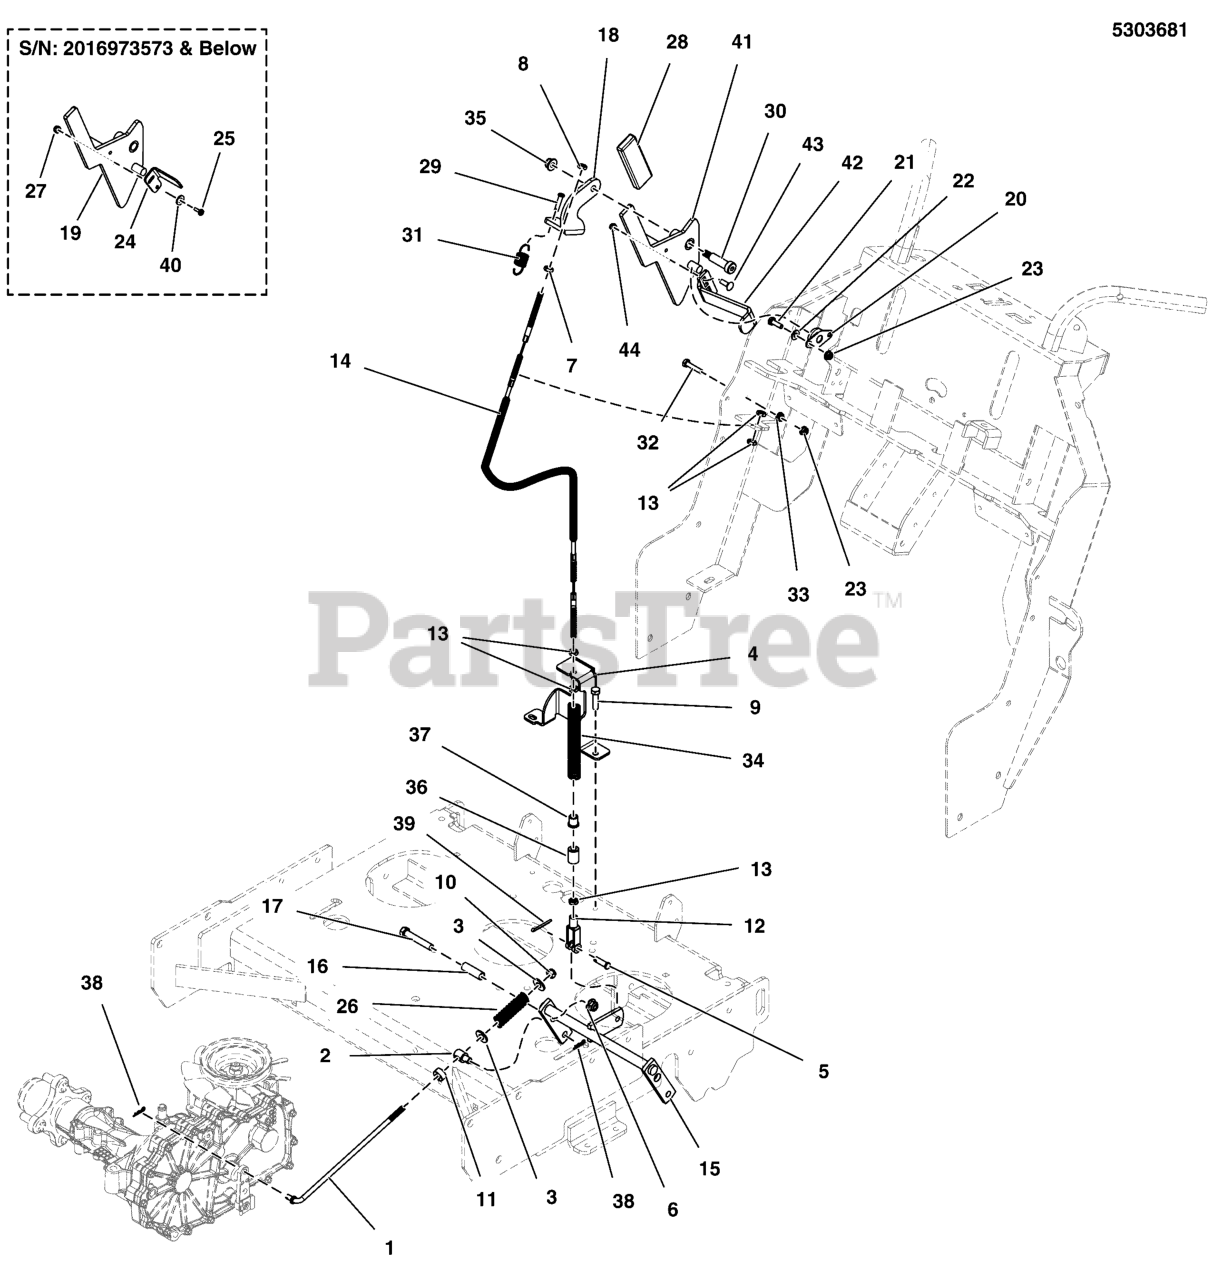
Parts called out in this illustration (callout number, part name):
1	ROD, BRAKE, SW35
2	ADJUSTER, BRAKE LINKAGE
3	WASHER, 5/16 USS
4	WELD, BRAKE CABLE MOUNT - BLK
5	PIN, CLEVIS, 5/16 X 1, PLATED
6	NUT, 3/8-16 HEX NYLOCK FLANGE
7	NUT, 5/16-18 HEX
8	NUT, 5/16-18 HEX NYLON LOCK
9	BOLT, 5/16-18 X 3/4, SELF TAPPING
10	NUT, 5/16-24 HEX NYLON LOCK
11	COLLAR, 5/16 SET
12	CLEVIS, 5/16-24, STEEL, CLEAR ZINC
13	NUT, 5/16-24 JAM
14	CABLE, PARKING BRAKE, 31" (787.9 cm)
15	WELD, BRAKE PIVOT - BLK
16	SPACER, .38 X .50 X 1.56
17	BOLT, 3/8-16 X 2-1/4" GD5 CZ
18	PLATE, OVER CENTER LINK
19	WELD, BRAKE LEVER, WALK - BLK
20	BEARING, 1/2 FLANGED, PLASTIC BALL
21	BOLT, 1/4-20 X 3/4 GD5 YZ
22	WASHER, 1/4 SAE
23	NUT, 1/4-20 HEX NYLOCK FLANGE
24	PLATE, SWITCH TAB - BLK
25	SCREW, #10-24 X 3/4 ROUND PHILLIPS
26	SPRING, COMP .480X.067X2.75
27	NUT, #10-24 HEX NYLON LOCK
28	GRIP, FOAM, 1/4 X 1 X 4.1
29	PIN, CLEVIS, 1/4 X 1, PLATED
30	BOLT-3/8-16 x 1-1/2, 1/2 SHOULDER
31	SPRING-EXT, .740 ODX2.025LGX.072WR, BLK
32	BOLT, 1/4-20 X 1-1/4, GD5
33	NUT, 1/4-20 HEX SERR. FLANGE
34	SPRING-COMP, .600ID X 5.50LG X .080WR
35	NUT, 3/8-16 HEX SIDE LOCK
36	SPACER, .32 X .75 X 1.06, PM
37	BUSHING, .38 X .75 X .75, PLASTIC
38	PIN, HAIR, .0585 X 1-1/8, 1/4 EYE, YZ
39	PIN, COTTER, 1/8 X 1-1/4
40	WASHER, #10 SAE
41	WELD, BRAKE HANDLE, F/SW35 - BLK
42	PLATE, NEUTRAL LOCKOUT - BLK
43	BOLT,1/4-20X0.750,GR5,STD NECK,SQ,ZC/CL
44	NUT, 1/4-20 HEX NYLOCK FLANGE
